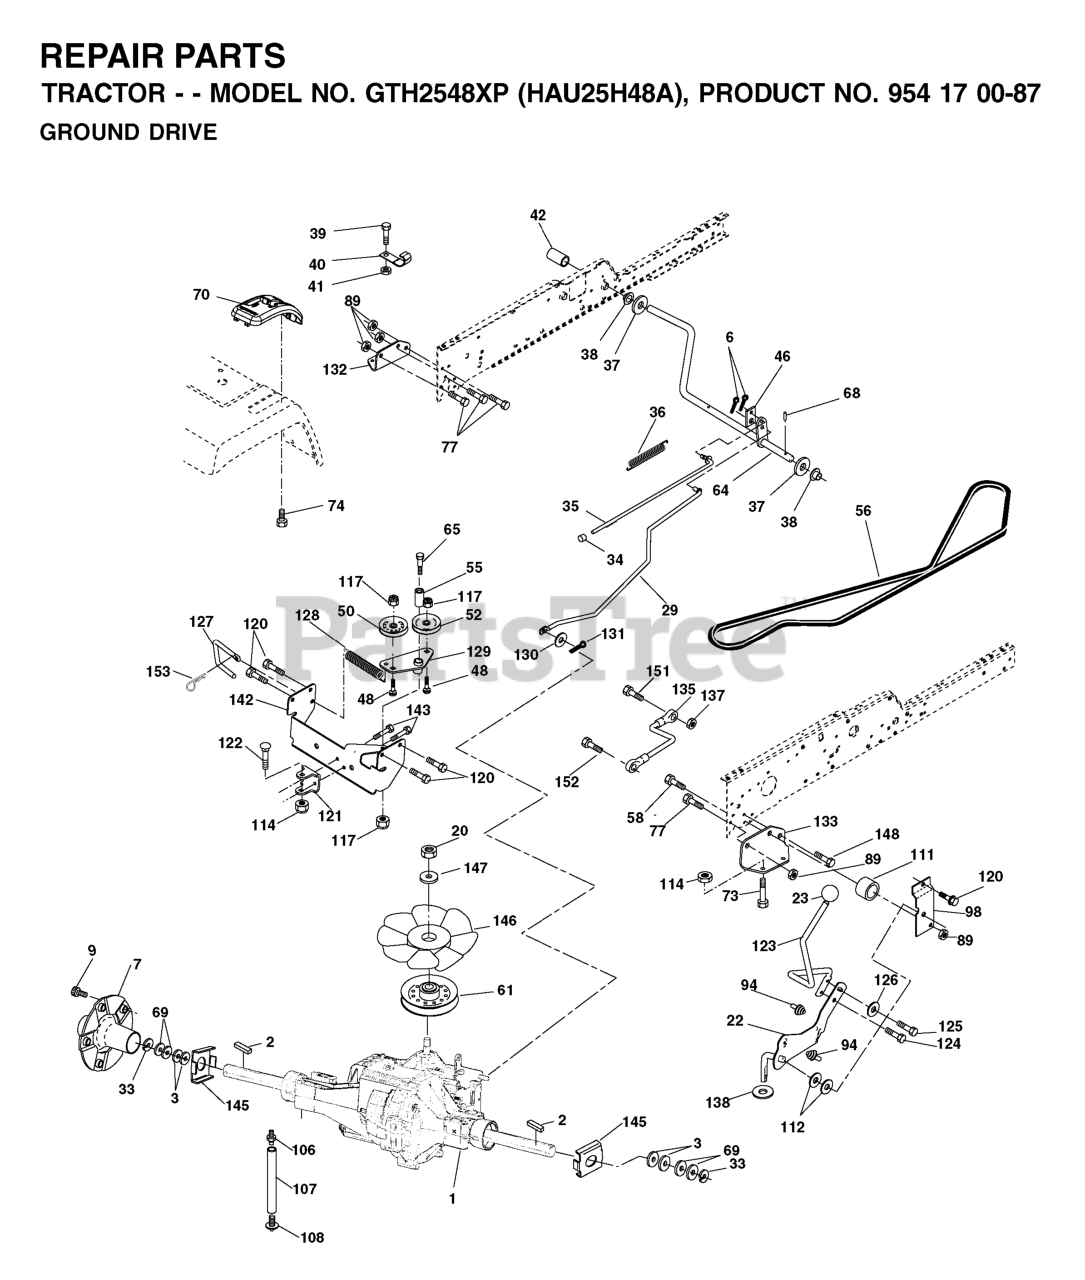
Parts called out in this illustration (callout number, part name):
2	SQUARE KEY
15	WASHER
17	SPRING.BRAKE.K46.GREEN
26	SPRING.RETURN.CRUISE
29	ROD.BRAKE.K46
35	ROD ROD.PARKINGBRAKE.GT.HUSQ/P
37	WASHER.HARDENED
42	PEDAL COVER T
50	IDLER.FLAT.910.OFFSET
51	NUT LOCK FLG 3/8-16 UNC
52	IDLER.V-GROOVE.910.OFFSET
56	V-BELT.MOWER.92.40.42/K46
64	SHAFT.ASM.PEDAL.BRK.CNTR
69	HAIRPIN.SOFT.ZINC.059X1.125
92	BOLT
99	ARM.PIVOTING.TCRD.GEN2.5.BAGGE
116	NUT LOCK HEX FLANGE 5/16-18
125	SCREW
143	SCR 5/16-18 X 1/2 SELFTAP ZN
153	RETAINER M
159	COTTER PIN
160	RETAINER CLIP
161	SPRING, RETURN LT
163	ROD.CONTROL.K57R.K46
166	NUT.PUSH.625
167	LATCH.BRAKE.SPRING
170	KEEPER.CENTER SPAN.1.688
183	SPACER AXLE
184	HANDLE.PARKING.BRAKE.H (BLK)
186	SPACER.RETAINER
187	WASHER 12/32X2X10GA
188	LINK.CLUTCH.GROUND DRIVE.LONG
189	BELLCRANK.GROUND.DRIVE.TEX.
190	KEEPER.BELLCRANK.DRIVE
196	SCREW 3/8-16X1
197	CLUTCH.ANTIROTATION.WIREFORM.
206	BRACKET.MOUNT.CRUISE.LATCH
207	LATCH.CONTROL.CRUISE.TEX
208	GEAR.SECTOR.CONTROL.CR
209	ROD ROD.CRUISECONTROL.GT.HUSQ/
210	ROCKER.ASM.PEDAL.CONTR
211	BEARING.NYLON
213	KNOB.CONTROL.CRUSIE.HU
214	PEDAL.FORWARD.PAD.TEX
215	PEDAL.COVER.REVERSE.CRD.X428BK
216	BRACKET.PULLEY.IDLER.W/TEX
221	RETAINER.SPRING.CLIP.H
222	WASHER 21/32 X 1-1/4 X 10 GA.
225	KEEPER.BELT.TRANSAXLE.K46
227	SCREW.THDROL.5/16-18X3/4.TTY
231	IDLER.V-GROOVE.1.688.OFFSET
325	TORQUE.STRAP.K46.LT.LH
326	BRACKET.TRQ.STP.K46.18"TIRE.RH
334	SWAY.ROD.BRACKET.K46
336	BOLT.5/16-18X1-3/4.FLANGED.HEX
